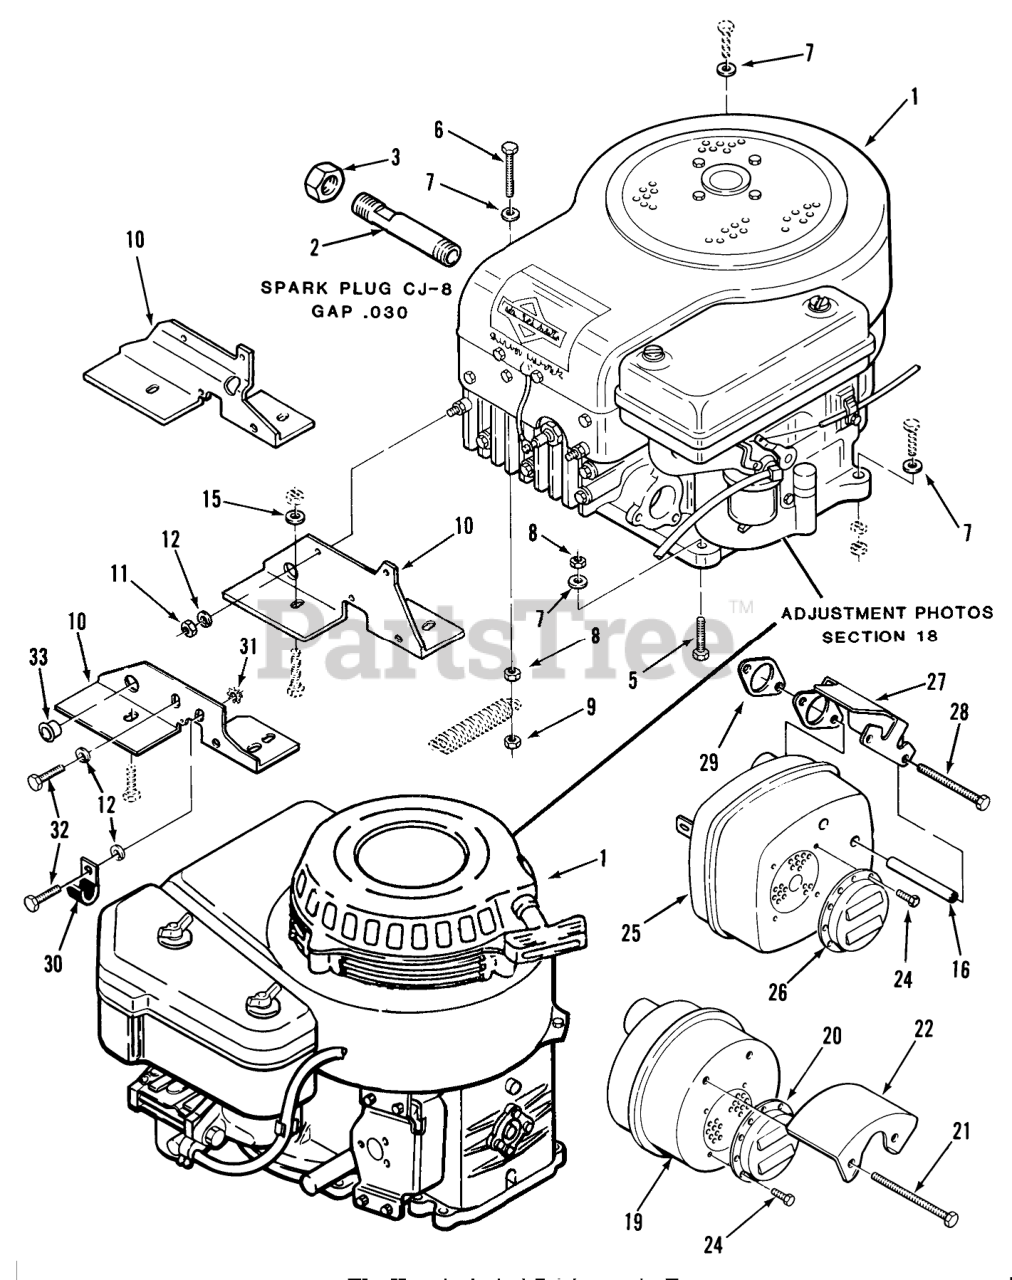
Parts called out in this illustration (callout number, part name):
2	PIPE-DRAIN B
3	Cap
5	Bolt
6	Bolt 5/16-18 x 2
7	WASHER 5/16 SAE
8	Nut
9	Nut
10	Engine Head Bracket 8 H.P. Models
11	Nut
12	Lockwasher
15	Washer
16	SPACER
19	Muffler-Chrome-211-A Only
20	Deflector 45 111-5 Only
21	Bolt, 5/16-18 x 1/4
22	Deflector-Chrome
24	SCRW-HX S.T.#8 X 3/8
25	MUFFLER
26	Muffler Deflector 112-C Only
27	HEAT-SHIELD
28	Bolt 8M x 1.25 x 110 112-C Only
29	GASKET
30	CLIP
31	Washer-Lock
32	Bolt 8M x 1.25 x 16 112-C Only
33	BUSHING-NYLON 1.093
